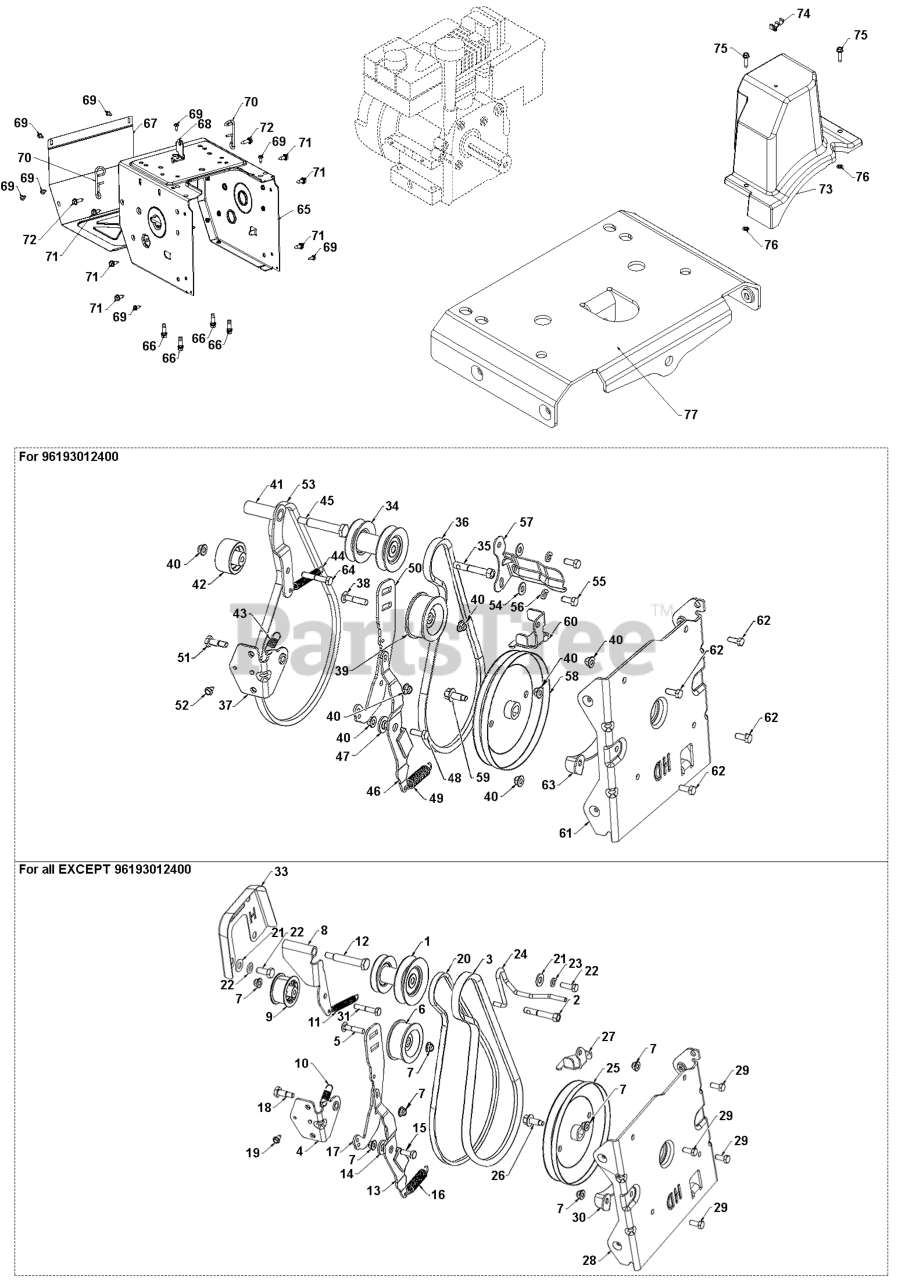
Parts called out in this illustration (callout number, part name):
1	PULLEY WELDMENT
2	BOLT.ENGINE.PULLEY
3	BELT 5L 39.15L
4	BRACKET WELDMENT, IDLER ARM ZI
5	BOLT 5/16-18 CARRIAGE 1.5L
7	NUT HEXAGON FLANGE 5/16-18 ST
7	NUTNYLOK.FLRANGE.5/16-18
8	ARM DRIVE IDLER CLEAR ZINC PLA
9	PULLEYIDLER.2.0.W/SPACER.CZ
10	SPRING IDLER RETURN
11	SPRING RETURN IDLER ARM
12	BOLT 5/16-24X2.25 HEX HEAD SHO
13	ARM IMPELLER BRAKE
14	BUSHING.BRAKE.ARM
15	BOLT HEXAGON BOLT 5/16-18 X 7/
16	SPRING EXTENSION - BRAKE
17	ARM IDLER BLACK ZINC
18	SCREW HEX HEAD SHOULDER
20	BELT 3L 39.68; POLY CORD
21	WASHER 11/32 X 11/16 X 14 GA T
21	WASHER M
22	SCREW 5/16-24 X .75 GR5
23	WASHER SPRING LOCK WASHER WITH
24	GUIDE BELT - 3L FRICTION, 5L I
24	GUIDE.BELT.5L.IMPELLER.3L.DRV
25	PULLEY IMPELLER DD 5L HD
26	SCREW HEXAGON HEAD FLANGE 3/8-
26	SCREW FLANGE HEAD CAP WITH DOG
28	BRACKET AUGER HOUSING INTERFAC
29	BOLT.FIN.HEX.5/16-18X3/4
29	SCREW HEXAGON HEAD SCREW 5/16-
30	BRACKET.BELT.KEEPER.LOWER.BLAC
31	BOLT, HEX 5/16-18X1-3/4
32	SCREW
33	Gutter
34	PULLEY WELDMENT
35	BOLT.ENGINE.PULLEY
36	BELT 5L 39.15L
37	BRACKET WELDMENT, IDLER ARM ZI
38	BOLT 5/16-18 CARRIAGE 1.5L
39	PULLEY IDLER
40	NUTNYLOK.FLRANGE.5/16-18
41	ARM IDLER DRIVE WELDMENT_HOT
42	PULLEY.IDLER.FLANG.2.O/SPACER
43	SPRING IDLER RETURN
44	SPRING RETURN IDLER ARM
45	BOLT 5/16-24X2.25 HEX HEAD SHO
46	ARM IMPELLER BRAKE
47	BUSHING.BRAKE.ARM
48	BOLT
49	SPRING EXTENSION - BRAKE
50	ARM IDLER BLACK ZINC
51	SCREW HEX HEAD SHOULDER
53	BELT 3L 39.68; POLY CORD
54	WASHER M
55	SCREW 5/16-24 X .75 GR5
56	WASHER.LOCK.HVY.HLCL.SPR.5/16
57	GUIDE BELT - 3L FRICTION, 5L I
58	PULLEY IMPELLER DD 5L HD
59	SCREW FLANGE HEAD CAP WITH DOG
61	BRACKET AUGER HOUSING INTERFAC
62	BOLT.FIN.HEX.5/16-18X3/4
63	BRACKET.BELT.KEEPER.LOWER.BLAC
64	BOLT, HEX 5/16-18X1-3/4
65	FRAME MS 668
66	BOLT 3/8-16X1-1/8
67	COVER COVER.FRAME MS668 ORANGE
68	BRACKET.SHIFTER.BZP
69	SCREW.HEX HEAD W/COLLAR 1/4-20
70	WIREFORM.SUPPORT.CABLE
71	BOLT.HEX.HD.WASHER.5/16-18X.75
72	SCREW HEX_SERR_HD_5_16-18X1.0
73	COVER BELT ASM HIGH CRANK
77	BRACKET.FRAME.SUP.LARGEENG.BLA
